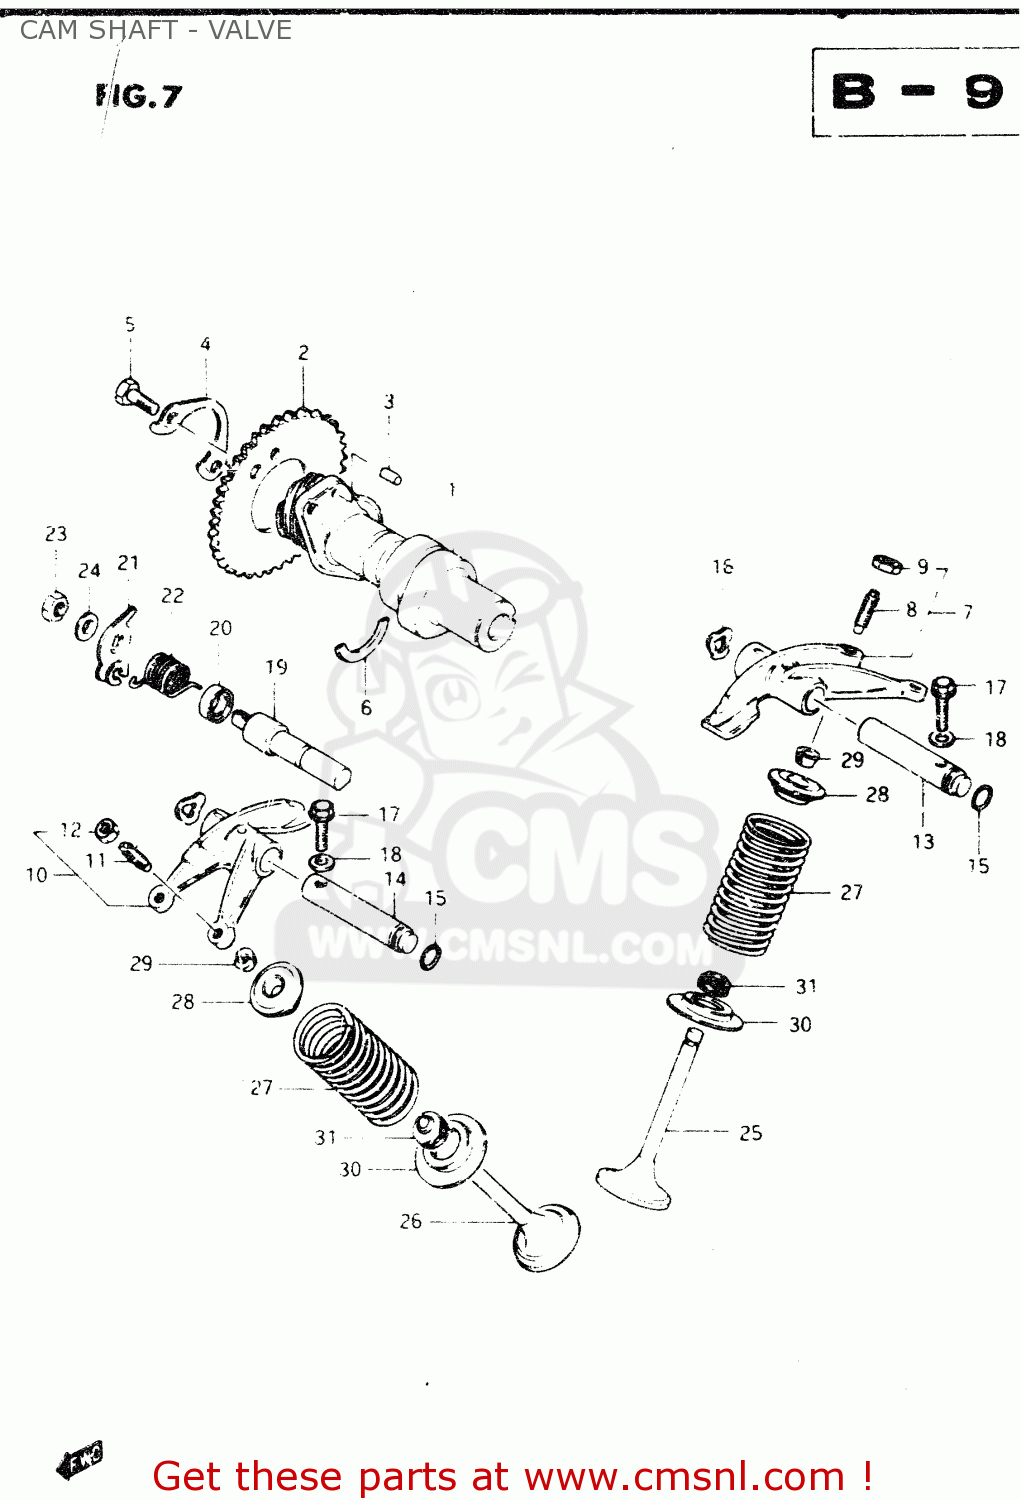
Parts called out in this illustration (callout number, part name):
1	CAMSHAFT
2	SPROCKET,CAMSHAFT(NT:42)
3	PIN
4	WASHER,CAM CHAIN SPROCKET
5	BOLT(6X12.5)
6	C RING
7	ARM,VALVE ROCKER
8	SCREW,TAPPET ADJUSTING
9	NUT,ADJUSTING
10	ARM,VALVE ROCKER,EXHAUST
11	SCREW,TAPPET ADJUSTING
12	NUT,ADJUSTING
13	SHAFT,VLV ROCKER ARM IN(L:91.5
14	SHAFT,VLV ROCKER ARM EXH(L:76)
15	O-RING
16	WASHER
17	BOLT 6X30
18	WASHER
19	SHAFT,DECOMPRESSION
20	OIL SEAL
21	LEVER,DECOMPRESSION SHAFT
22	SPRING
23	NUT 8MM
24	WASHER,8.5X16X
25	VALVE,INTAKE
26	VALVE,EXHAUST
27	SPRING,VALVE
28	RETAINER,VALVE SPRING
29	COTTER VALVE
30	SEAT,VALVE SPRING
31	OIL SEAL
